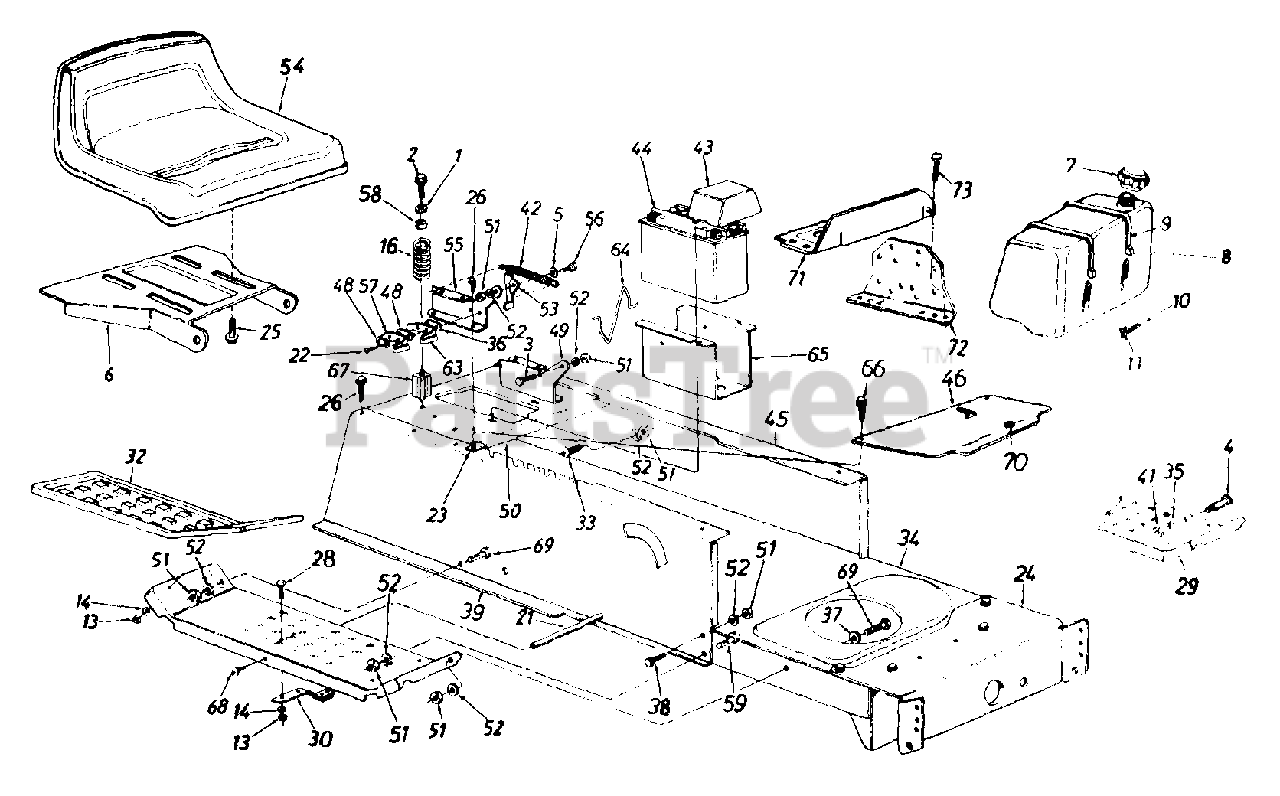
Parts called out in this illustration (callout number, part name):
1	Fl-Wash. .344" I.D. x .875"
2	Hex Wash. Hd. Tap Scr. 5/16-18 x 3.25" Lg.
3	Shld. Bolt .437" Dia. x .162"
4	Shld. Bolt .50" Dia. x .84"
5	Spr-Wash. .445" I.D. x .75
7	Fuel Cap
8	Fuel Tank
9	Tie Strap
10	Fuel Line
13	Hex Nut 1/4-20 Thd.
14	L-Wash. 1/4" I.D.
16	Compression Spring
21	Running Board Rod
23	Speed Nut #10Z
24	Front Pivot Brkt.
25	Hex Tap Scr. 3/8-16 x .75"
26	Hex Wash. Hd. AB-Tap Scr. 5/16 x .75" Lg.
28	Carriage Bolt 1/4-20 x .62"
29	Running Board (R.H. & L.H.)
30	Blade Brake Ass'y.
32	Rubber Foot Pad - L.H.
33	Truss Mach. Scr. 5/16-18 x .75" Lg.
34	Lower Frame
35	L-Wash. 3/8" I.D.
36	Insulator Boss Plate
37	Fl-Wash. .344" I.D. x .625" O.D.
38	Hex Bolt 5/16-18 x .75" Lg.
42	Extension Spring 5.31" Lg.
43	Battery Cover
44	12-V Battery
45	Upper Frame - L.H.
46	Shift Cover
48	Insulator Plate
52	L-Wash. 5/16" I.D.
53	Seat Lift Brkt.
54	Seat
56	Shld. Bolt .437" Dia. x .268"
57	Spring Switch
59	Hex Wash. TT-Tap Scr. 5/16-18 x 7/8" Lg.
63	Safety Switch (Seat)
64	Battery Tray Clip
65	Battery Tray
66	Truss Mach. B-Tap Scr. #10 x .5" Lg.
67	Spring Spacer
68	Pan Hd Cutting Scr. 5/16-18 x .75" Lg.
69	Hex Bolt 5/16-18 x .75" Lg.
70	Snap Bushing
